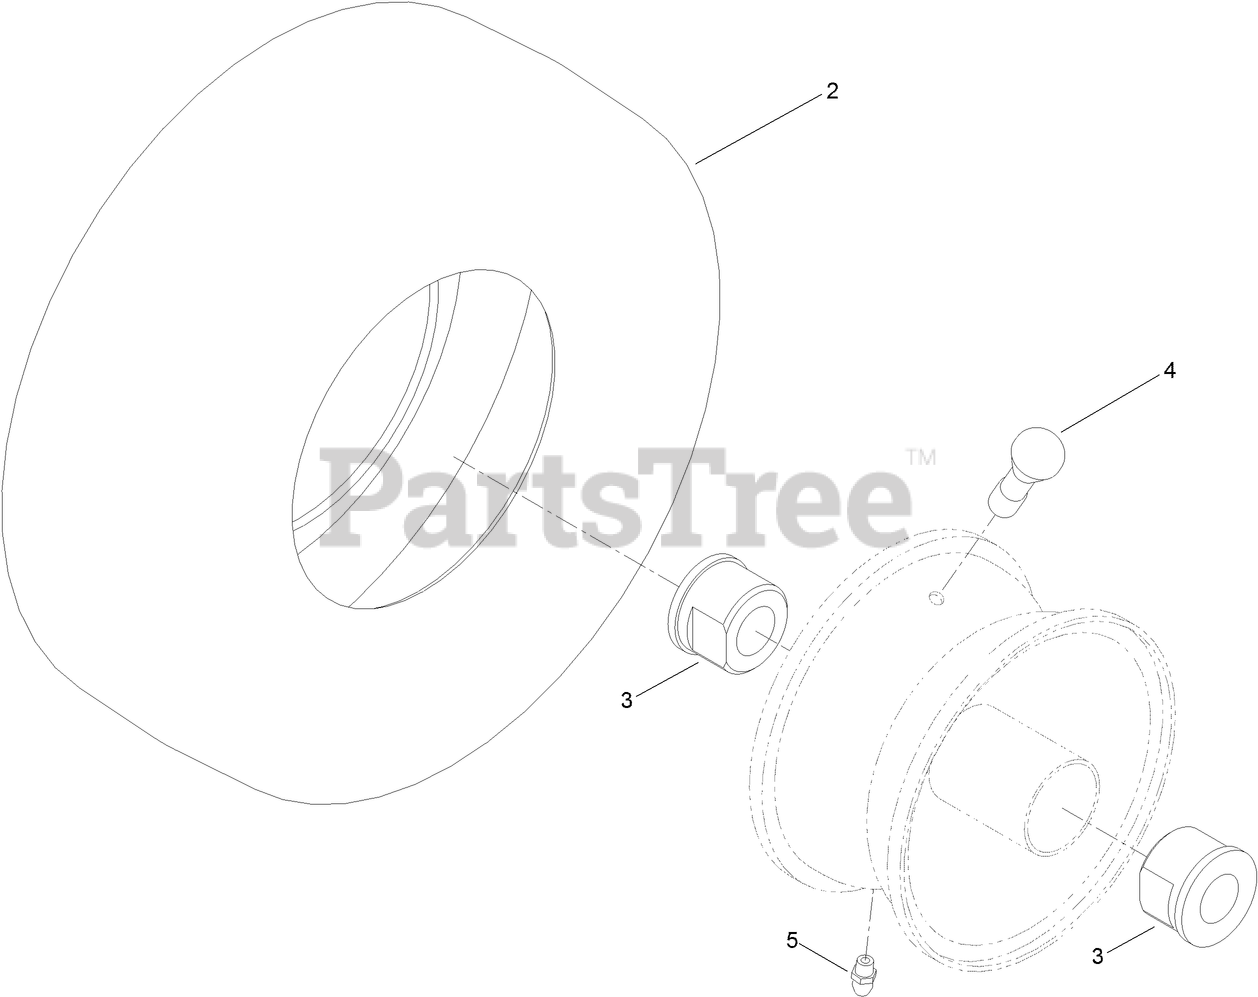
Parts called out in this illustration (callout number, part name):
3	BUSHING-FLANGE
5	FITTING-GREASE
99	TUBE-INNER
